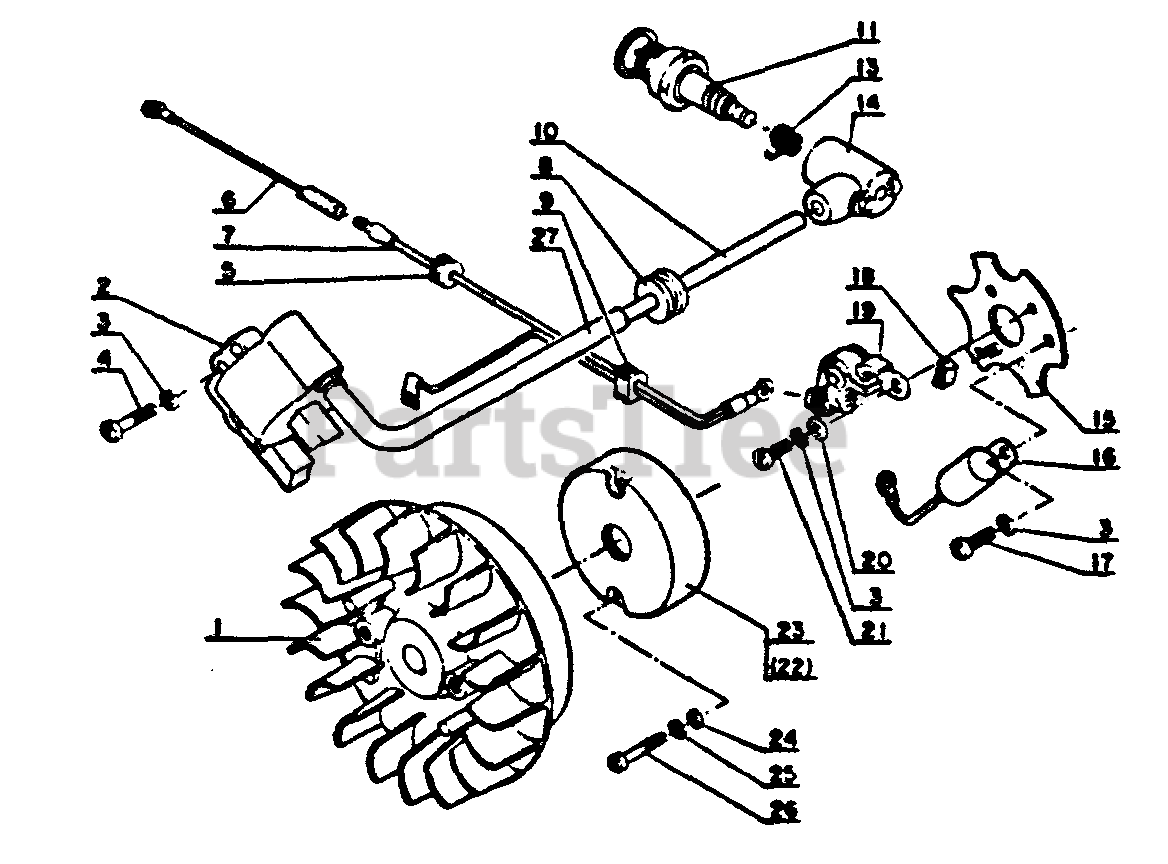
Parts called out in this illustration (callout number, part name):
1	FLYWHEEL
2	COIL, IGNITION
3	LOCKWASHER - 4
4	SCREW - 4X18
5	GROMMET
6	LEAD - GROUND
7	LEAD - GROUND
8	GROMMET
9	GROMMET
11	SPARK PLUG -- BM-6A
13	TERMINAL, SPARK PLUG CAP
14	CAP, SPARK PLUG
15	PLATE, STATOR
16	CONDENSER
18	OILER
19	CONTACT POINT SET
20	WASHER - 4
21	SCREW - 4X8
23	COVER, BREAKER
24	WASHER - 3
25	LOCKWASHER - 3
26	SCREW - 3X25
27	TUBE
28	STUD
29	STUD
30	WASHER - 4
32	SEAL
